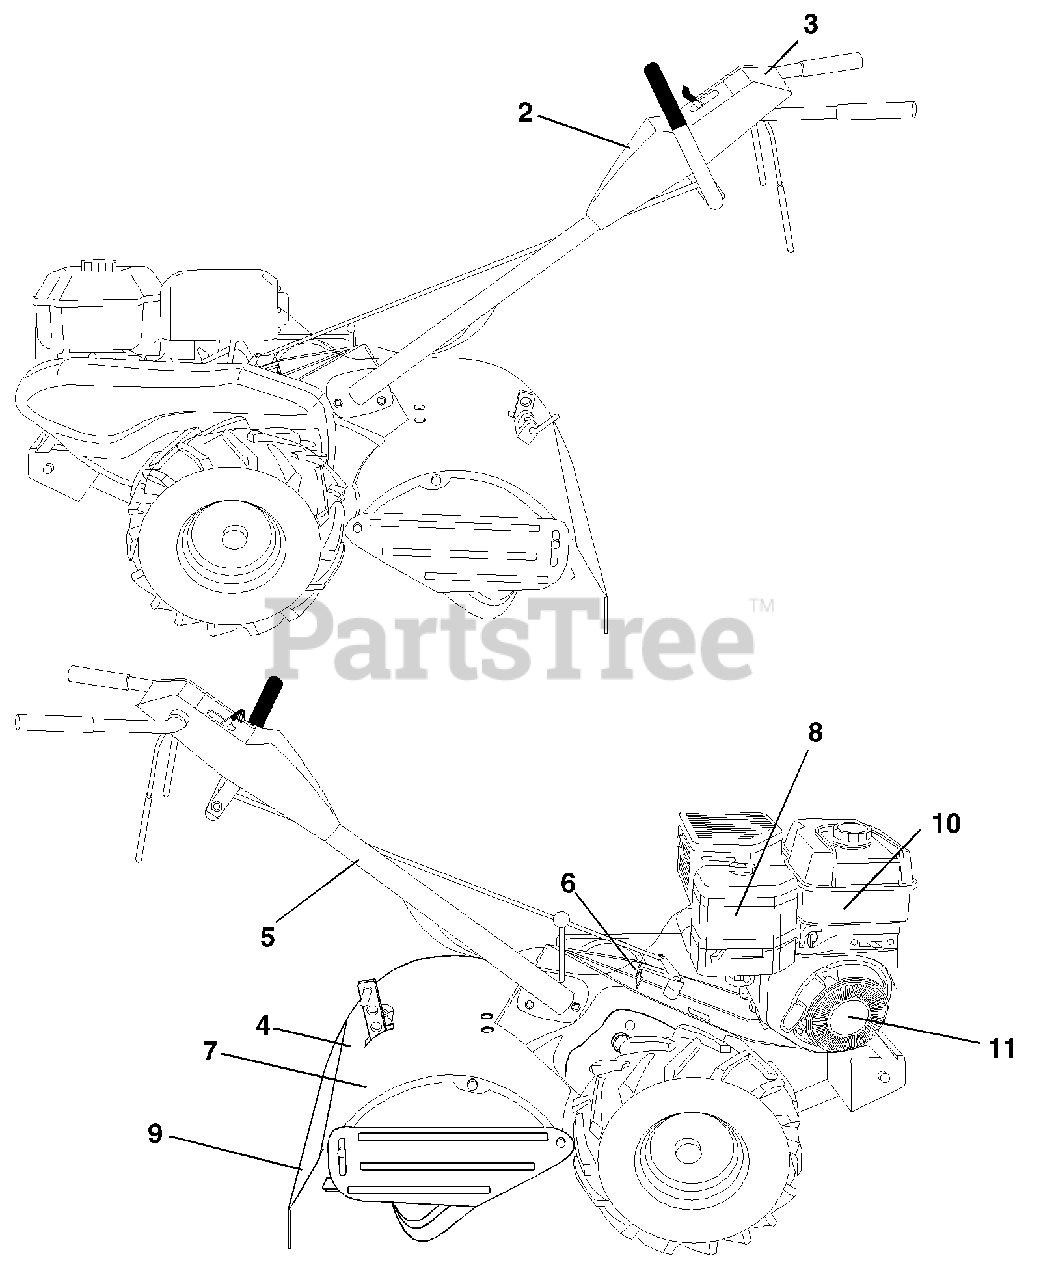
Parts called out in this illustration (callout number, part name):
2	Decal, CNTRL PNL
3	Decal, Control Tine
4	Decal, Tine Shield
5	Decal, Hand Placement
6	Decal, Shift Indicator
7	Decal, Warning
8	Decal, Engine B&S 6.5 HP
9	Decal, Warning, Rotating Tines
10	Decal, Engine Intek REF
11	Decal, Rewind Intek #274350
